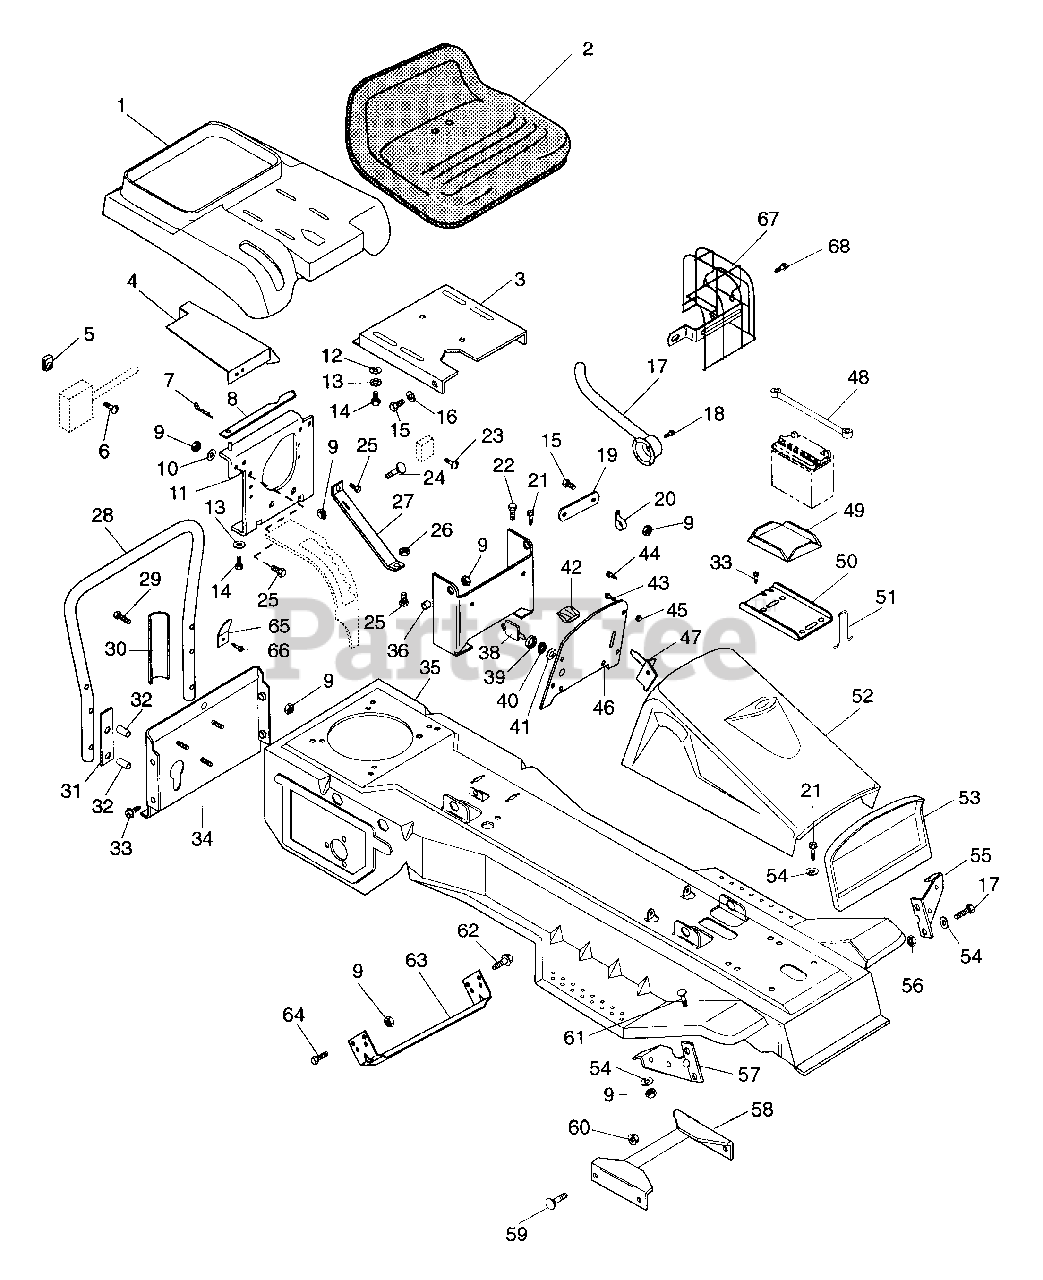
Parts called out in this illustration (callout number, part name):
1	ENGINE COVER
2	SEAT-V450
2	SEAT V-350
3	SEAT BRACKET
4	BAFFLE
5	NUT-KEPS 10-24 PL
6	SCR-MCH 10-24X.38 SLTOR PAN PL
7	PIN-HAIR INT .08X.18X1.18
8	SEAT HOLD DOWN
9	NUT-LK .312-18 GR A PL
10	WSHR-LK-INT .313X.030 PL
11	SEAT LEG ASSEMBLY
12	WSHR-FL-STL .38X.875X.083 PL
13	WSHR-LK .312X.097 PL HVY
14	BLT-HEX .31-18X.75 PL GR5
15	BLT-HEX .31-18X.75 PL GR2
16	WSHR-FL-STL .344X1.125X.063PL
17	SPACER .328X.750X.375
18	SCR-TAP 8-32X.38 SL HWH PL 23
19	STRAP
20	CLIP
21	SCR-TAP .250-20X.50 HXSLHDPL
22	BLT-HEX .31-18X.50 PL GR2
23	SCR-MCH 10-24X.62 SLRH PL
24	BLT-RDHDSQNK .312-18X.62 PL
25	BLT-HEX .25-20X.50 PL GR2
26	NUT-LK-CTR .250-20 PL
28	TUBE
28	STANDUP TUBE
29	BLT-HEX .31-18X1.50 PL GR2
29	BLT-HEX .31-18X2.75 GR5
30	BRACE
31	PLATE-BACKING
32	SPACER .50 X .32 X 1.00
33	SCR-TAP .312-18X.50 HWH PL TR
34	BACK COVER
35	FRAME WITH DECALS
36	SPACER BUSHING .5 X .32 X .163
37	SEAT PIVOT BRACKET
38	KEY SET
39	CAP - IGNITION SWITCH
40	NUT-PANEL .625-32 GRECO
41	WSHR-LK-INT .625X.045 PL
43	SCR-TAP 10-24X.375 CRPH 1A
44	SCR-TAP 10-12X.50 CRPH PL A BL
45	PLASTIC GROMMET
46	DASH PANEL-RM
47	THROTTLE CONTROL
48	BATTERY STRAP
49	RUBBER PAD
50	BATTERY TRAY
51	HOOK
53	GRILLE INSERT & SHELL ASSEMBLY
54	WSHR-FL-STL .323X.625X.062 PL
55	L H FENDER BRACE
56	NUT-LK-TWIN .312-18 PL
57	RH FENDER BRACE
58	FRAME BRACE
59	BLT-RDHDSQNK .312-18X.62SHTPL
60	NUT-FLG. .312-18 PL
61	BLT-RDHDSQNK .31-18X.75 GR5 PL
62	SCR-TAP .312-18X1.50 HWH PL TR
63	FRAME BRACE
64	BLT-HEX .31-18X.63 PL GR 2
65	CLIP
66	SCR-TAP 12-24X.50 HWH PL TR
67	MUFFLER GUARD (B&S#495945)
68	SCREW (B&S#094887)
